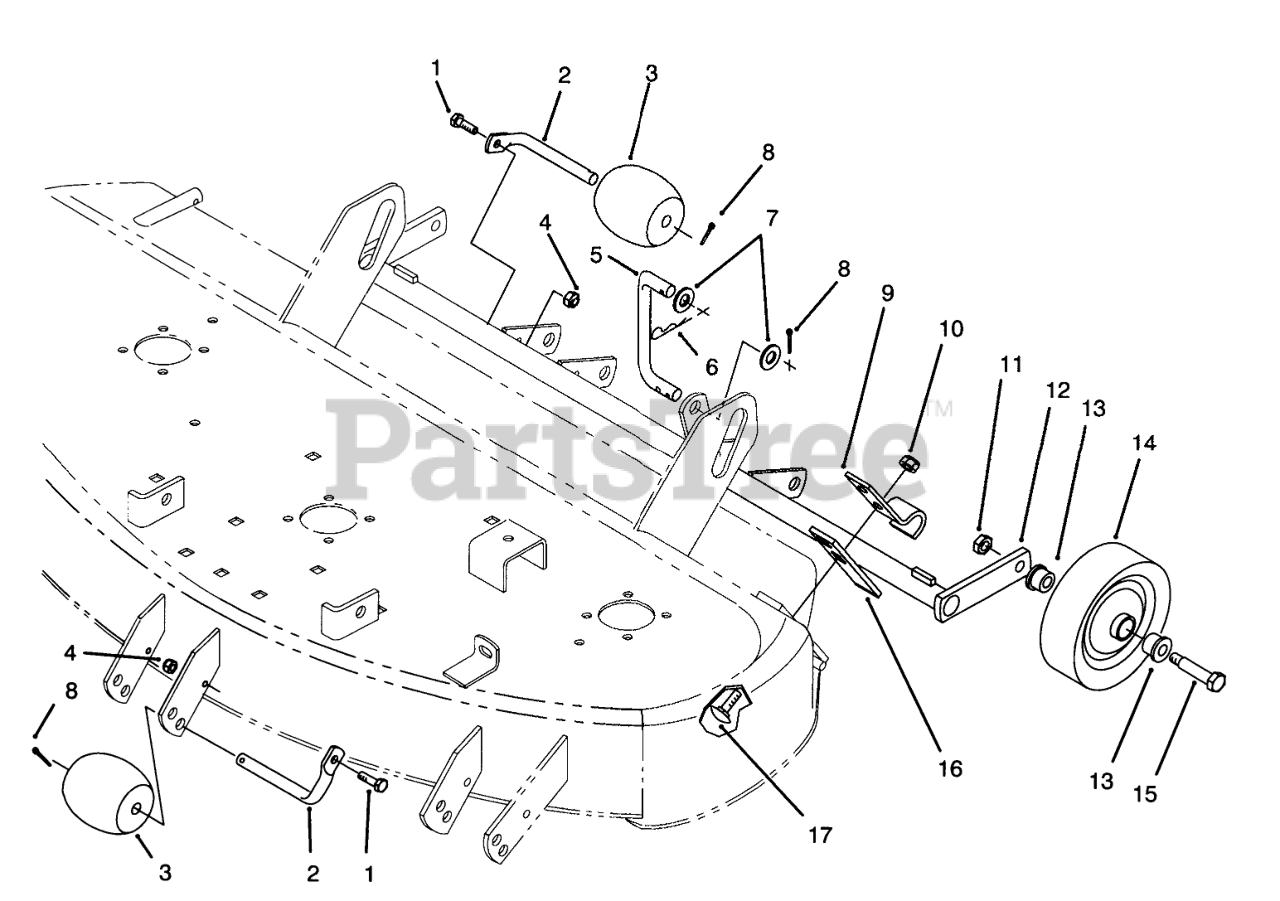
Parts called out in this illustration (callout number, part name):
1	SCREW-HH
2	SHAFT-ROLLER
3	ROLLER
4	NUT-LOCK, NI
5	LINK-REAR
6	Hairpin
7	WASHER-FLAT
8	PIN-COTTER
9	Clamp
10	NUT-LOCK, NI
11	NUT-HEX
12	SUPPORT-GAGE WHEEL
13	BEARING
14	Assembly-Wheel (Incl. Ref. #13)
15	BOLT-SHOULDER
16	Bar
17	SCREW-CARR
